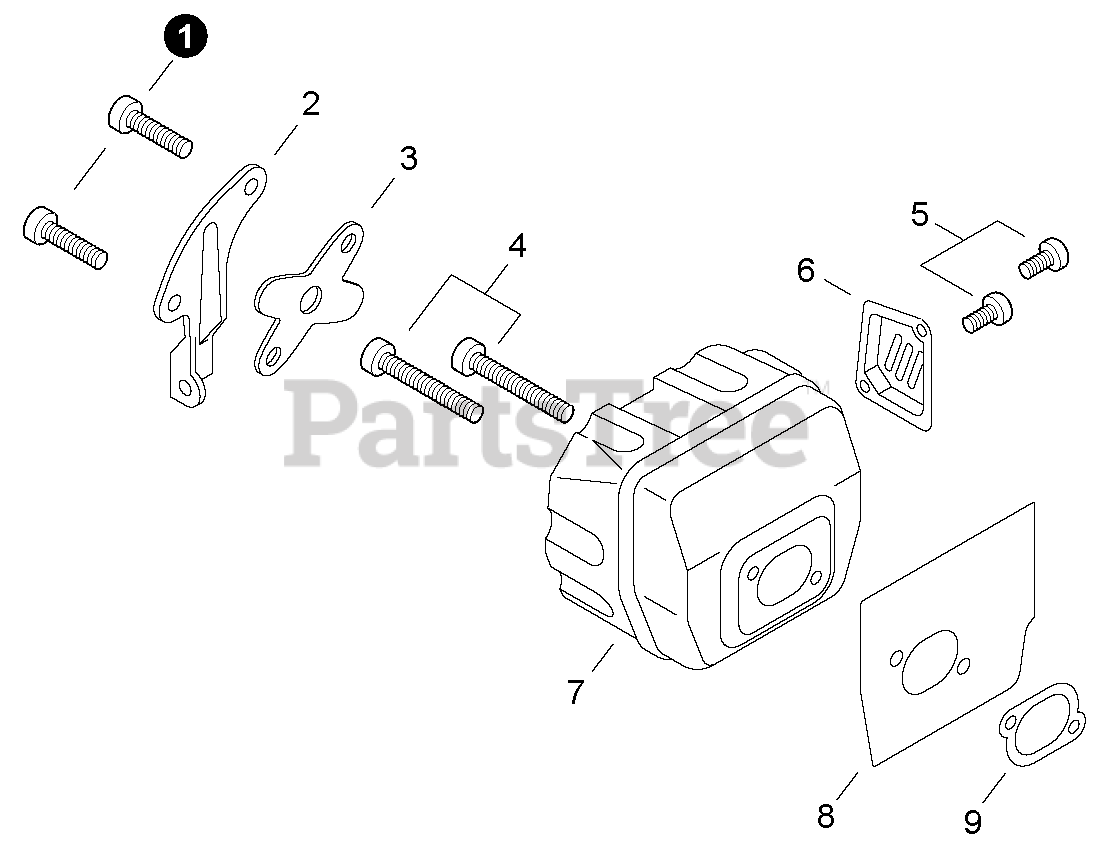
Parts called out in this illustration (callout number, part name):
1	SCREW - 5X12
2	BRACKET, MUFFLER
3	COVER, MUFFLER
4	SCREW - 5X20
5	SCREW - 4X10
6	GUIDE, EXHAUST
7	MUFFLER
8	SHIELD, EXHAUST
9	GASKET, EXHAUST
